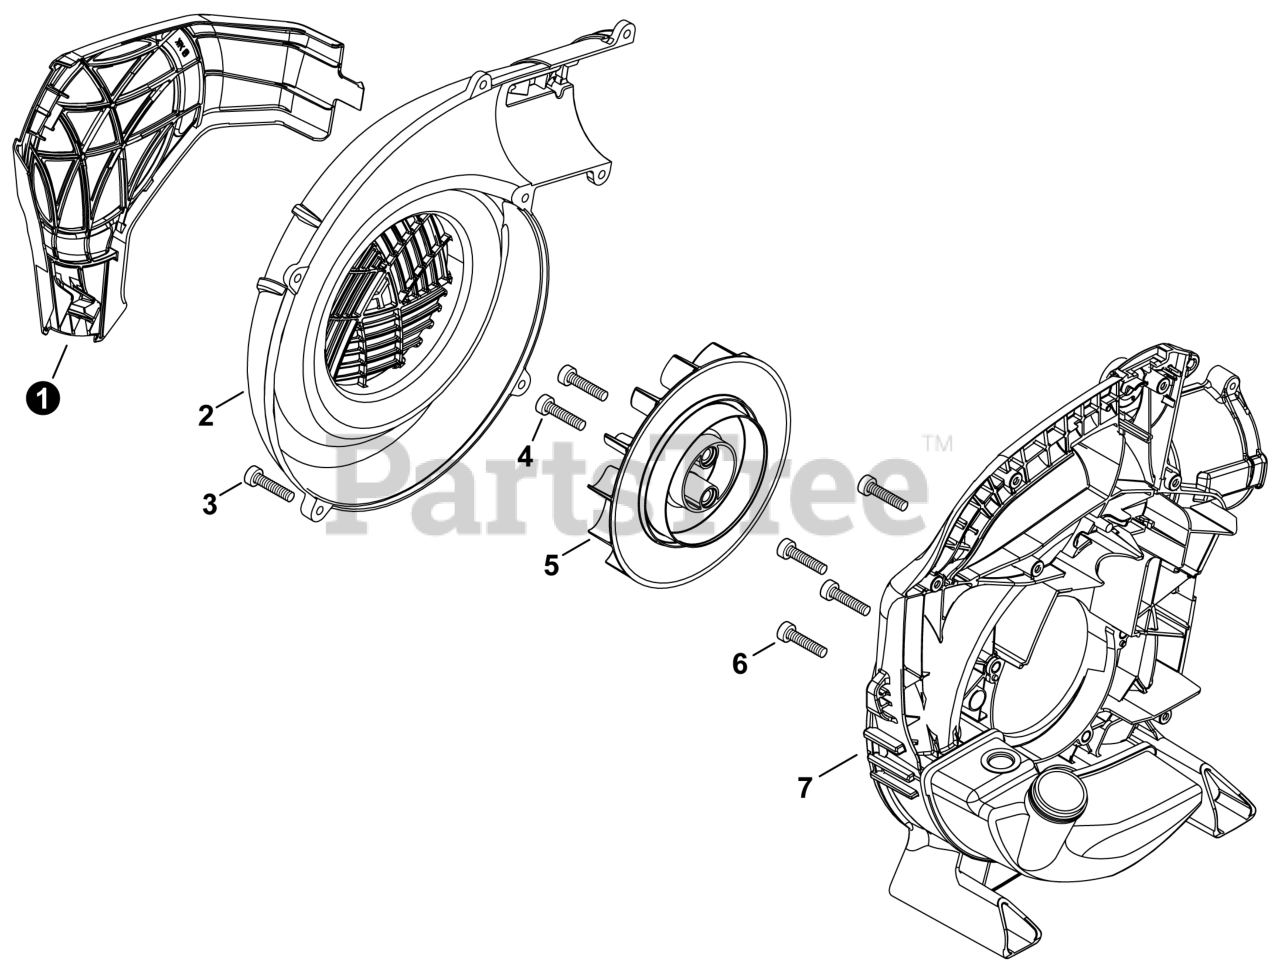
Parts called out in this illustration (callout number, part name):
1	GUARD, DEBRIS
2	COVER, FAN CASE
3	BOLT, TORX 5x20
4	BOLT, TORX 6x20
5	FAN, BLOWER
6	BOLT, TORX 5x16
7	CASE, FAN
